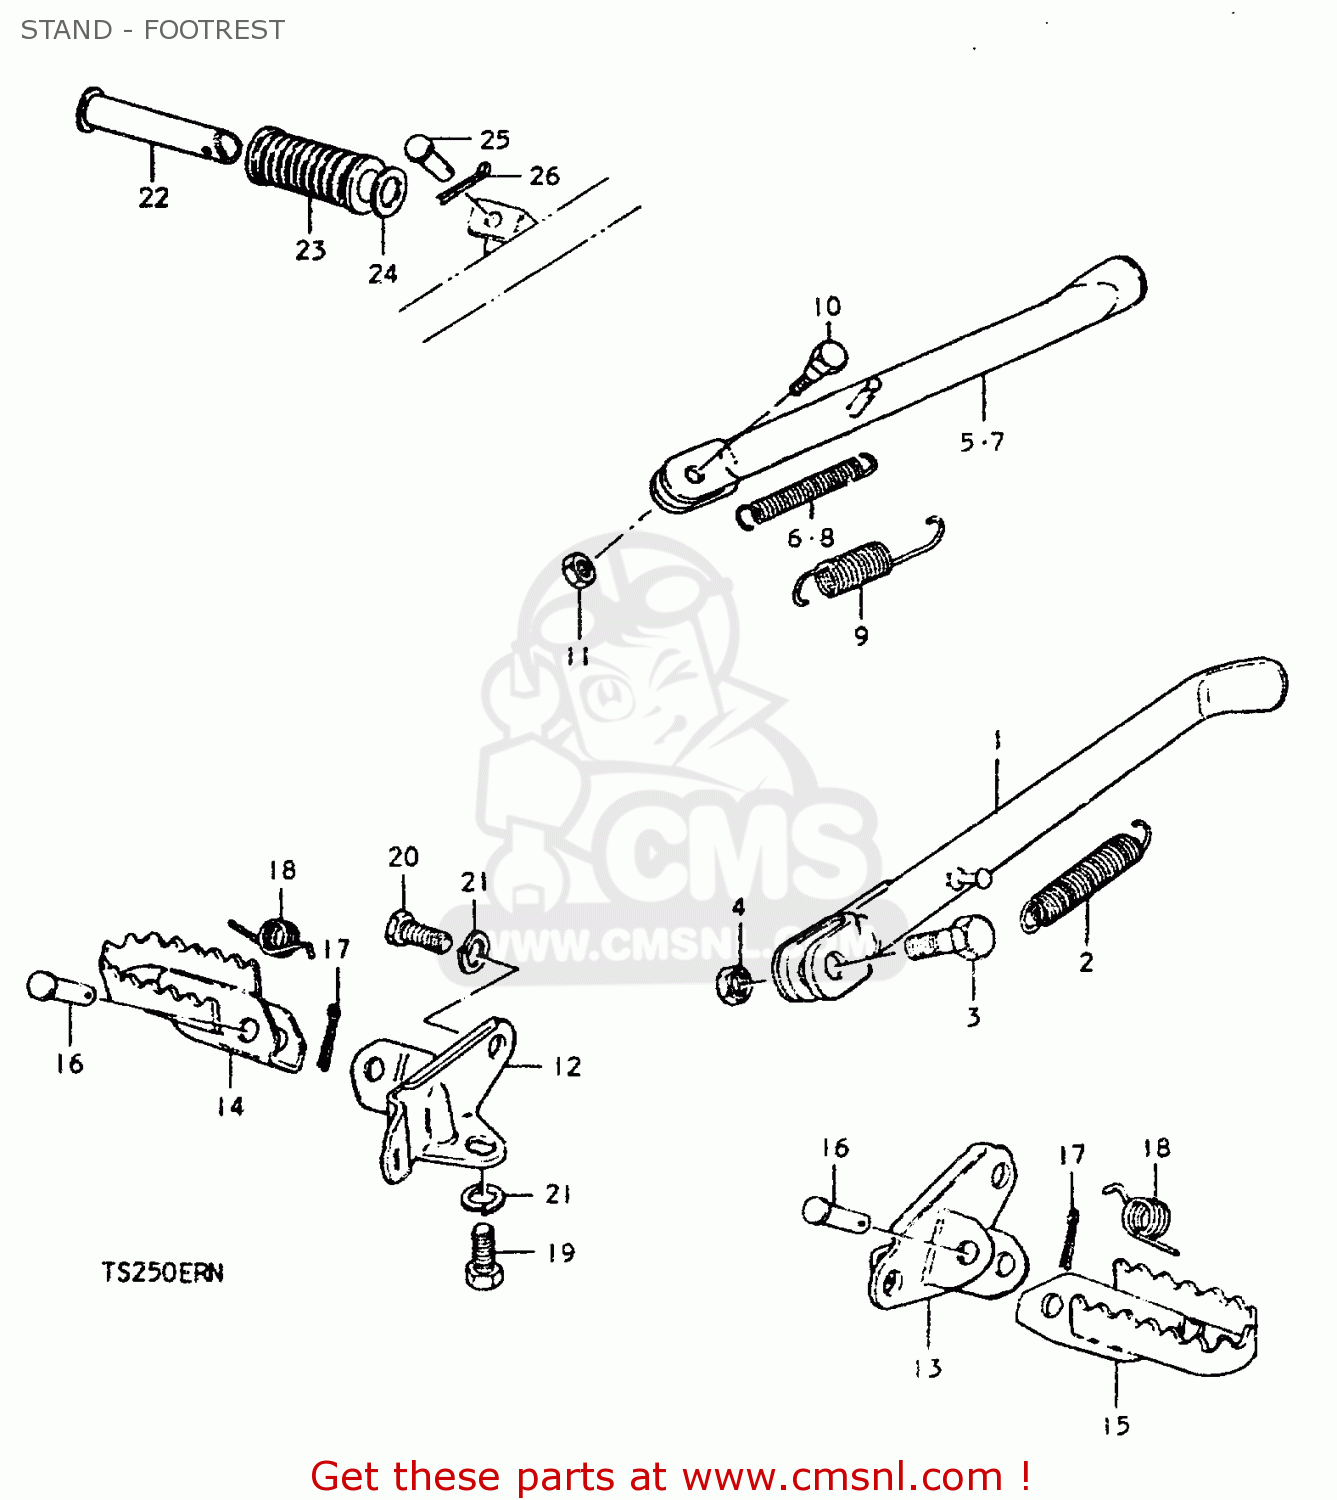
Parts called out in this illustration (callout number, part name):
1	STAND,PROP
2	SPRING
3	BOLT(10X30)
4	NUT
12	HOLDER,FRONT FOOTREST,RIGHT
13	HOLDER,FRONT FOOTREST
14	FOOTREST,FRONT
15	FOOTREST
16	PIN
17	PIN 20X20
18	SPRING
19	BOLT
20	BOLT 8X16
21	WASHER,LOCK,8.
22	BAR,FOOTREST RUBBER
23	RUBBER,PILLION FOOTREST
24	WASHER (19.5X32X2)
25	PIN
26	PIN 20X20
